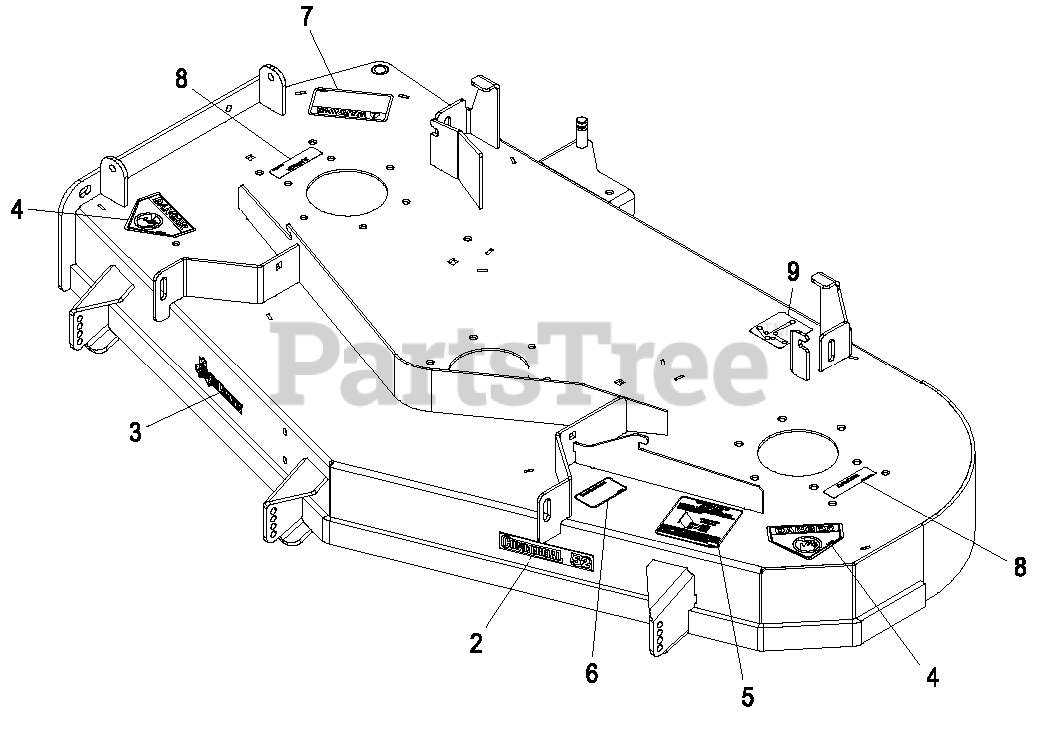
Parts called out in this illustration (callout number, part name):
2	DECAL,COMMERCIAL 52
4	DECAL-DANGER
5	DECAL,ANTISCALP
6	DECAL,BOLT TORQUE
7	DECAL-WARNING, DISCHARGE
8	DECAL-COVER, MISSING
9	DECAL-ROUTING, BELT
